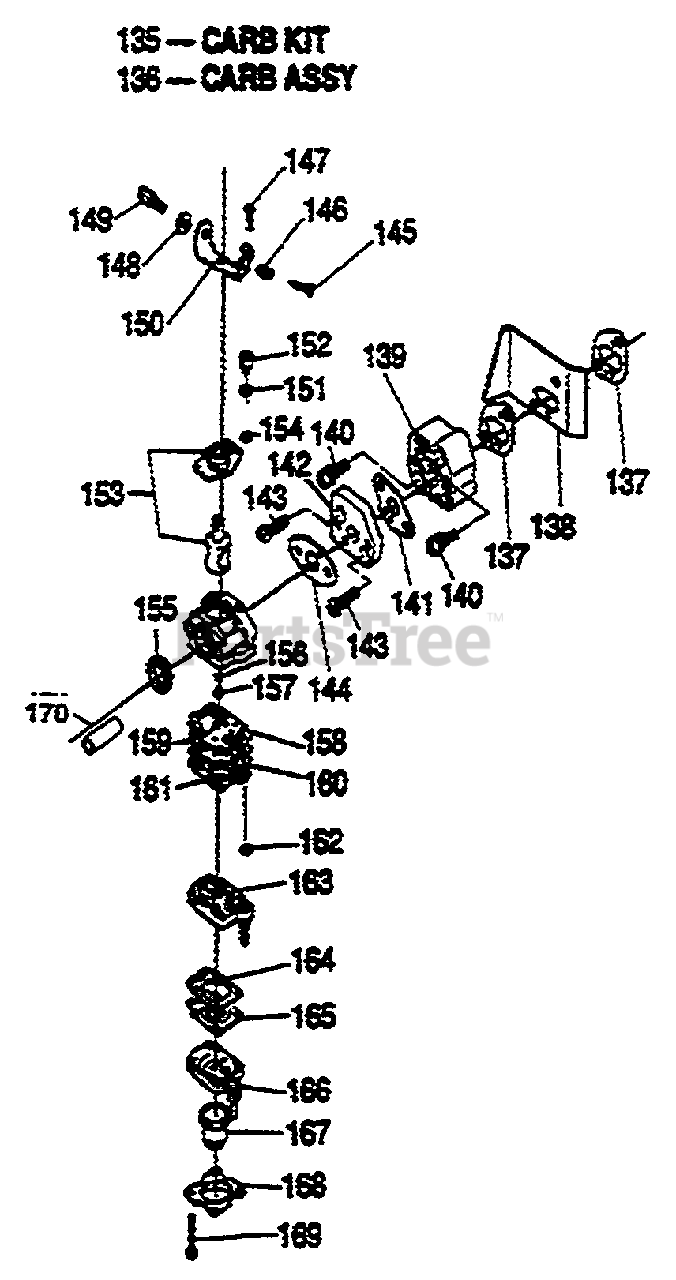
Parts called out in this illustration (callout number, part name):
136	CARB ASSY
137	GASKET, INSULATOR
139	INSULATOR
140	SCREW & WASHER
141	GASKET, CARB.
144	GASKET, CARB.
145	SCREW, IDLE
146	SPRING, IDLE
148	NUT, CABLE ADJ.
149	ADJUSTER, CABLE
153	VALVE, THROTTLE
154	RING, SWIVEL
158	GASKET, PUMP
159	DIAPHRAGM
162	SCREEN, INLET
163	BODY ASSY.
164	GASKET, DIAPH.
165	DIAPHRAGM
166	BODY, PUMP
167	PUMP, PRIMER
168	COVER, PRIMER
169	SCREW, COVER
171	JET HIGH ALT.
172	JET HIGH ALT.
